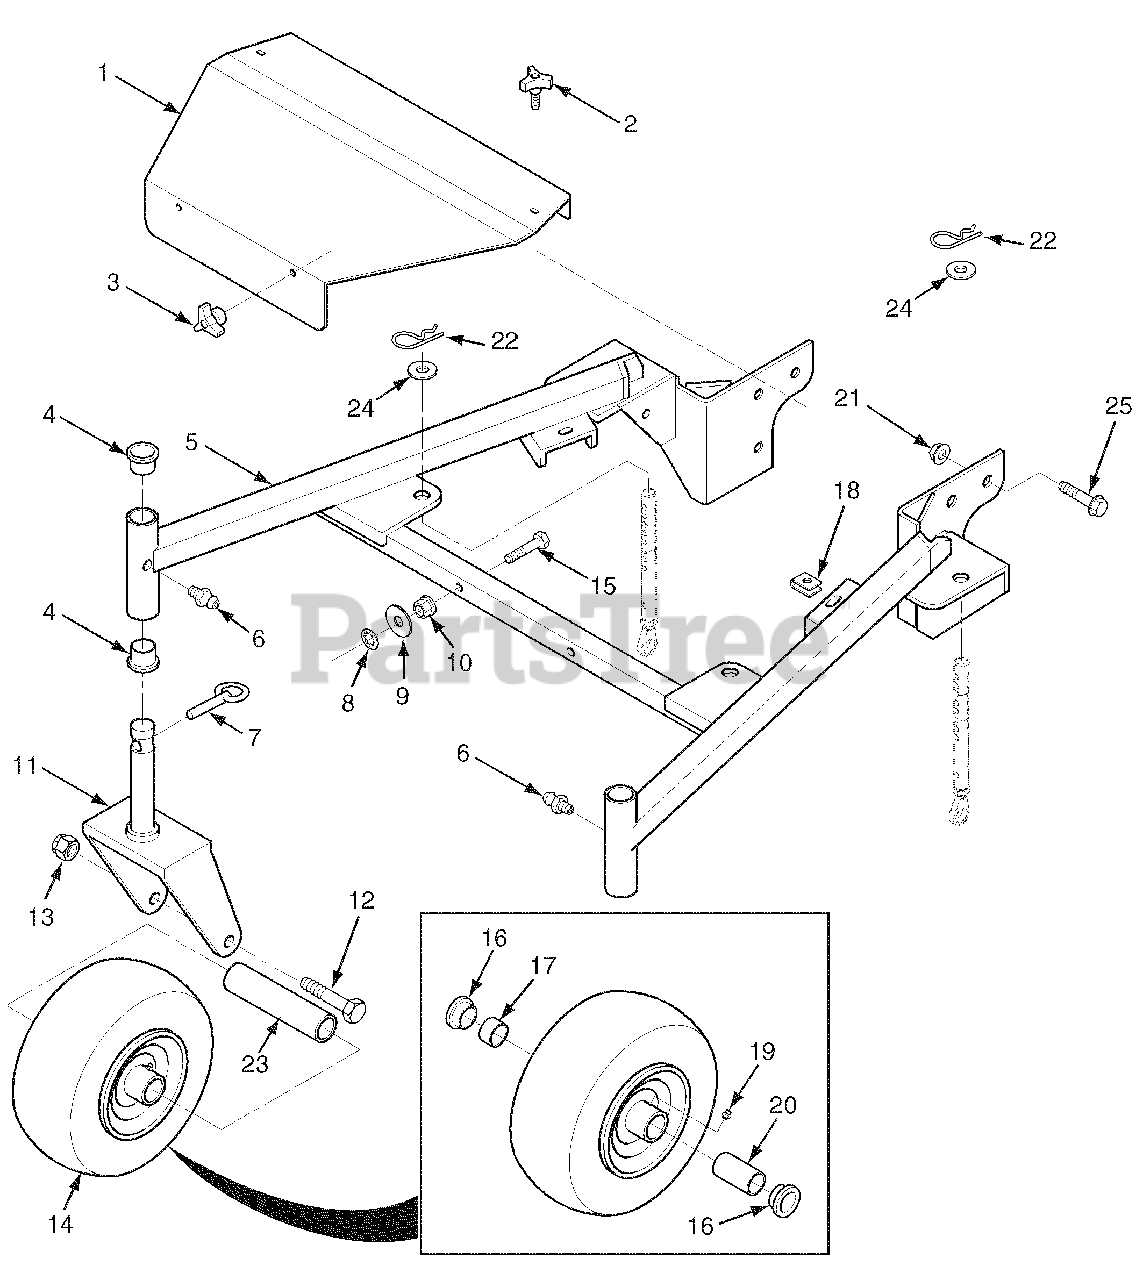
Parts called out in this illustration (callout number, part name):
1	52" Belt Cover With Decal
2	Knob With Stud
3	Knob, Deck Cover Mounting
4	Bushing, Caster
5	Frame Weldment, Deck Mounting - 52"
6	Grease Fitting Str. 1/4-28 Self Tap
7	Quick Pin, .438" Dia.
8	Nut, Push-On - 3/8" Dia.
9	Flatwasher, 3/8"
10	Nut, 3/8-16 Serrated Flange Hex Head
11	Yoke, Caster Wheel
12	Capscrew, Hex Head 1/2-13 x 6-1/2"
13	Locknut, 1/2-13 Elastic Stop
14	Flat Free Tire Assy.
15	Capscrew, Hex Head 3/8-16 x 2-1/4"
16	Retainer
17	Roller Bearing
18	U-Nut, 3/8-16
19	Grease Fitting Str.1/4-28
20	Roller Bearing .625 x 3.25"
21	Nut, 1/2-13 Spiralock
22	Hair Pin Cotter, .177 x 3-1/4"
23	Sleeve, Caster Wheel
24	Flatwasher, 5/8"
25	Capscrew, 1/2-13 x 1" Serrated Flange Hex Head
